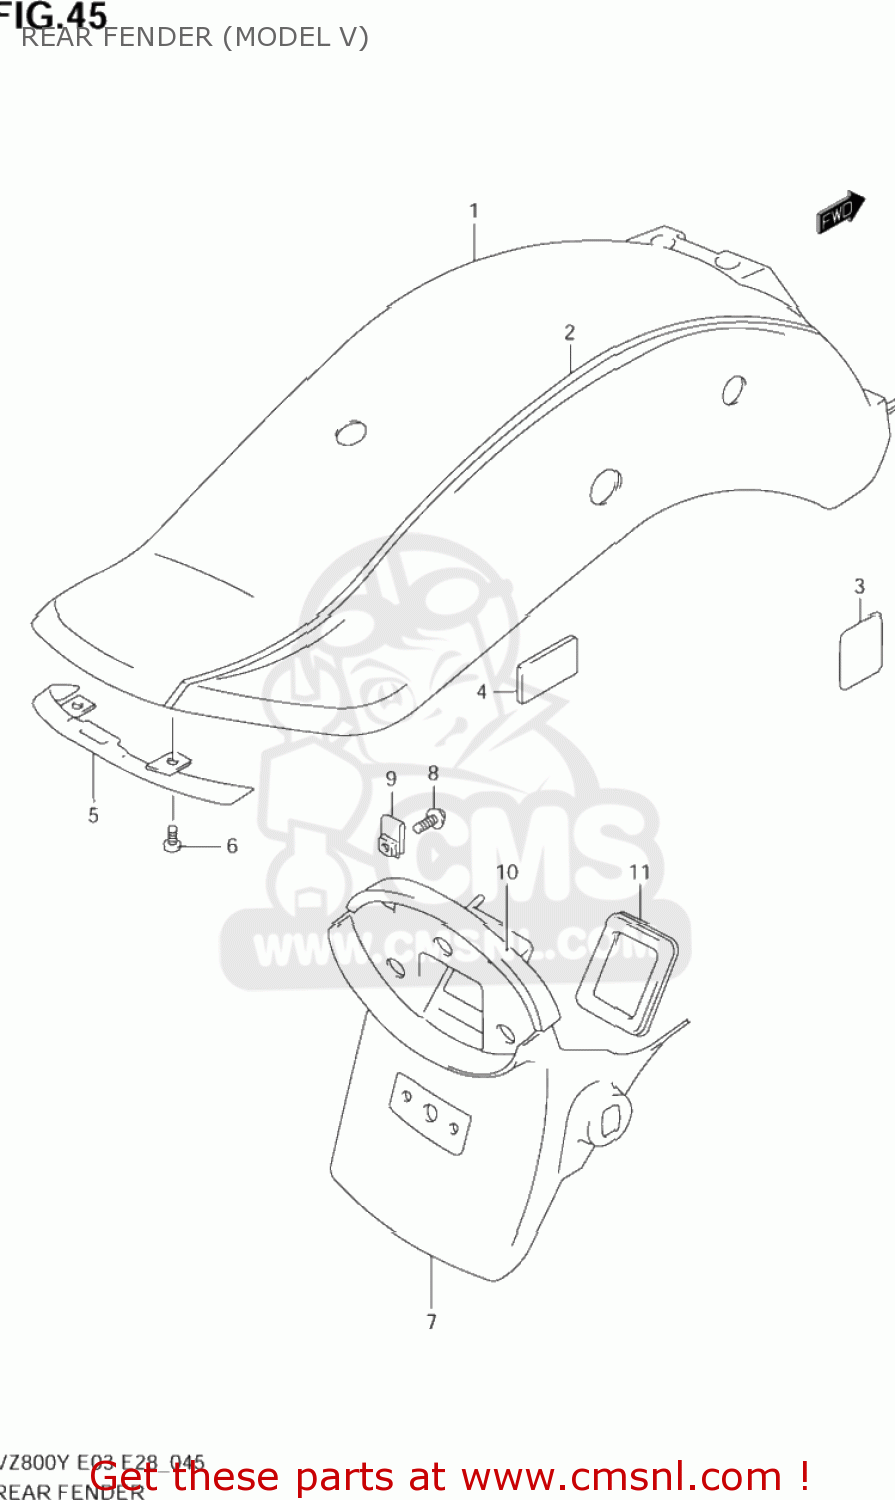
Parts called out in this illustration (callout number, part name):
1	FENDER,RR
2	TAPE SET,RR FENDER
3	PAD
4	CUSHION
5	COVER,RR FENDER RR
6	SCREW
7	EXTENSION,RR FENDER
8	SCREW
9	PLATE,FRAME COVER
10	CUSHION,RR FENDER EXTENSION
11	CAP,RR FENDER EXTENSION
